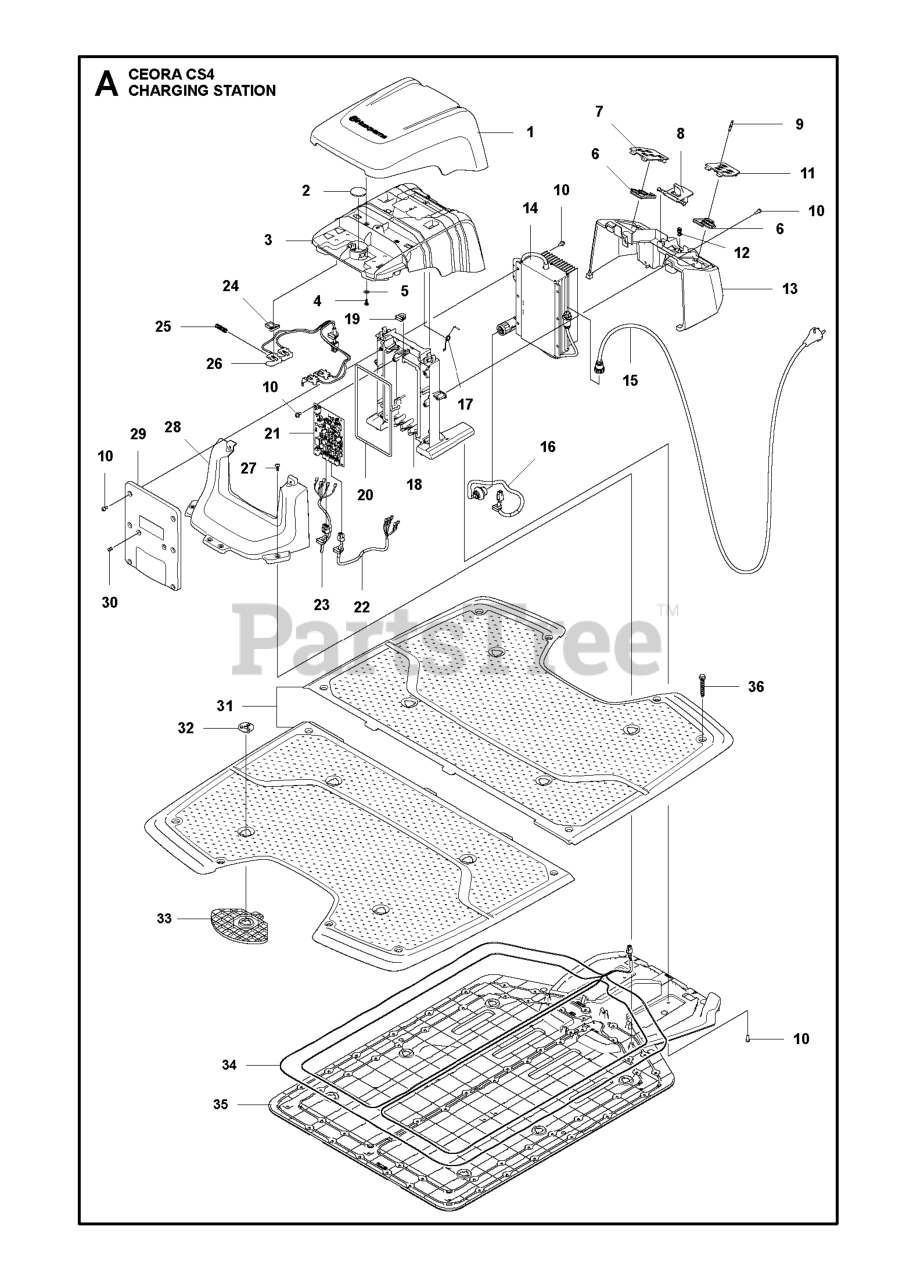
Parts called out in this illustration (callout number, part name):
1	CAP CHARGING STATION DESIGN CA
2	MAGNET D40X3
3	FRAME
4	SCREW 14MM
5	WASHER
6	PANEL LOWER TERMINAL PANEL
7	PANEL UPPER TERMINAL PANEL
8	BUTTON OPEN BUTTON CHARGING ST
9	TERMINAL TERMINAL CHARGING STA
10	SCREW
11	PANEL UPPER TERMINAL PANEL LH
12	SPRING STOP BUTTON
13	HOUSING
14	POWER UNIT
15	WIRING ASSY PSU PRIMARY SIDE
15	WIRING ASSY
16	WIRING ASSY PSU SECONDARY SIDE
17	SPRING
18	STAND
19	GROMMET GROMMET P3 CHARGING ST
20	SEALING STRIP P3 SEALING STRIP
21	PRINTED CIRCUIT ASSY PCBA CS B
22	WIRING ASSY GENERATOR BOARD 6P
23	WIRING ASSY GENERATOR BOARD 8P
25	SPRING SPRING CAP
26	WIRING ASSY CHARGING STATION P
27	SCREW ITXPANT
28	HOUSING
29	LID TOWER FRONT LID
30	LENS DIODE
31	PLATE CHARGING PLATE UPPER SYM
32	COUPLING BAYONET
33	SUPPORT BASE PLATE SUPPORT
34	WIRING ASSY CHARGING PLATE N/F
35	BASE FN FIELD BASE PLATE
36	SCREW ANKERBOLT JCP:JAB06/0805
